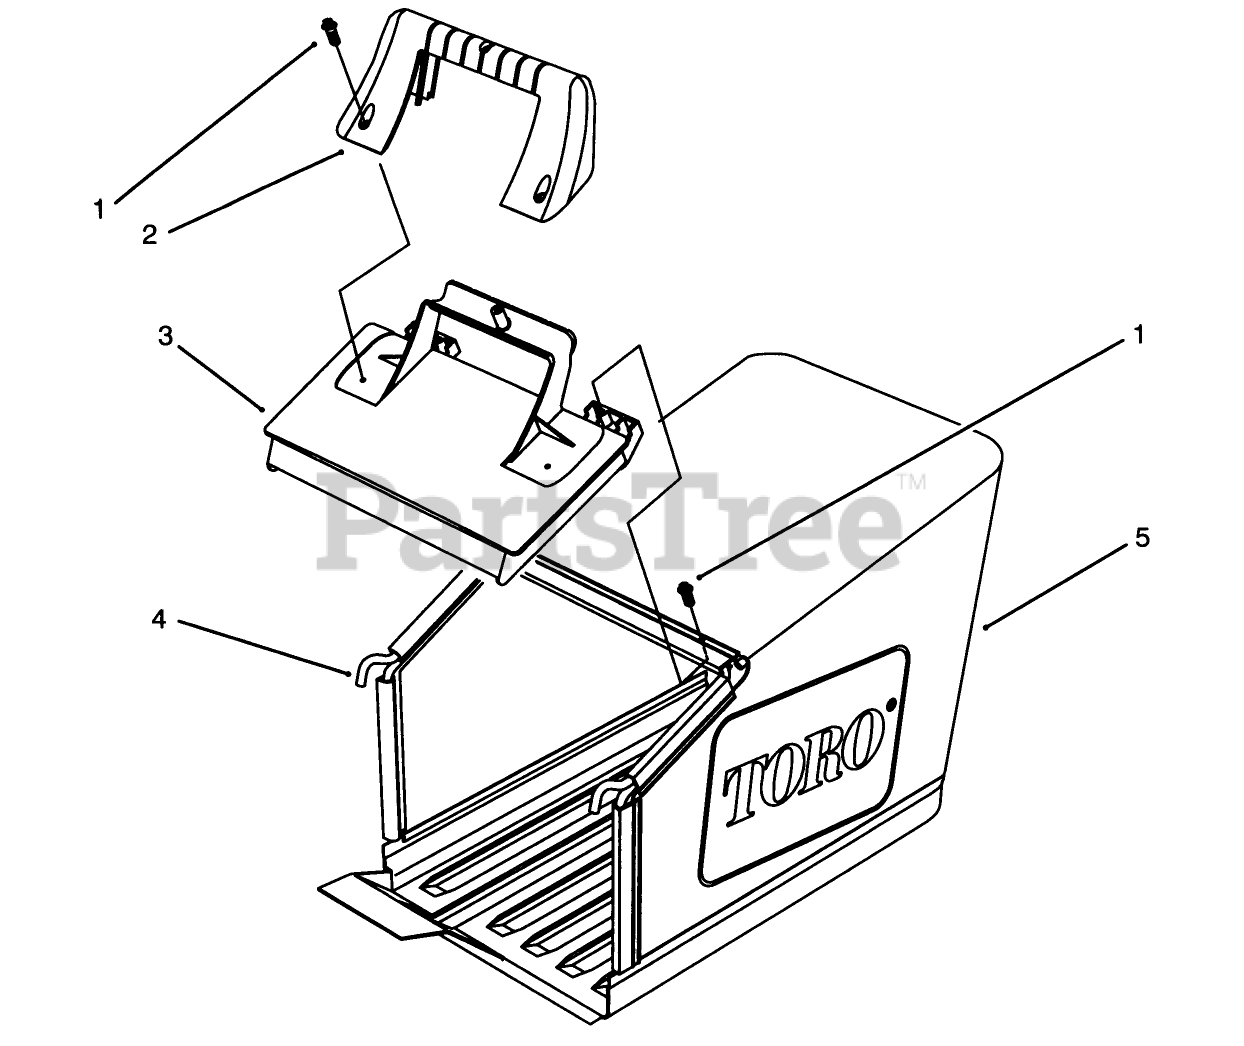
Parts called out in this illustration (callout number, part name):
1	SCREW-PPH
2	HANDLE-DOOR
3	DOOR-BAG
4	Frame
5	BAG-GRASS
